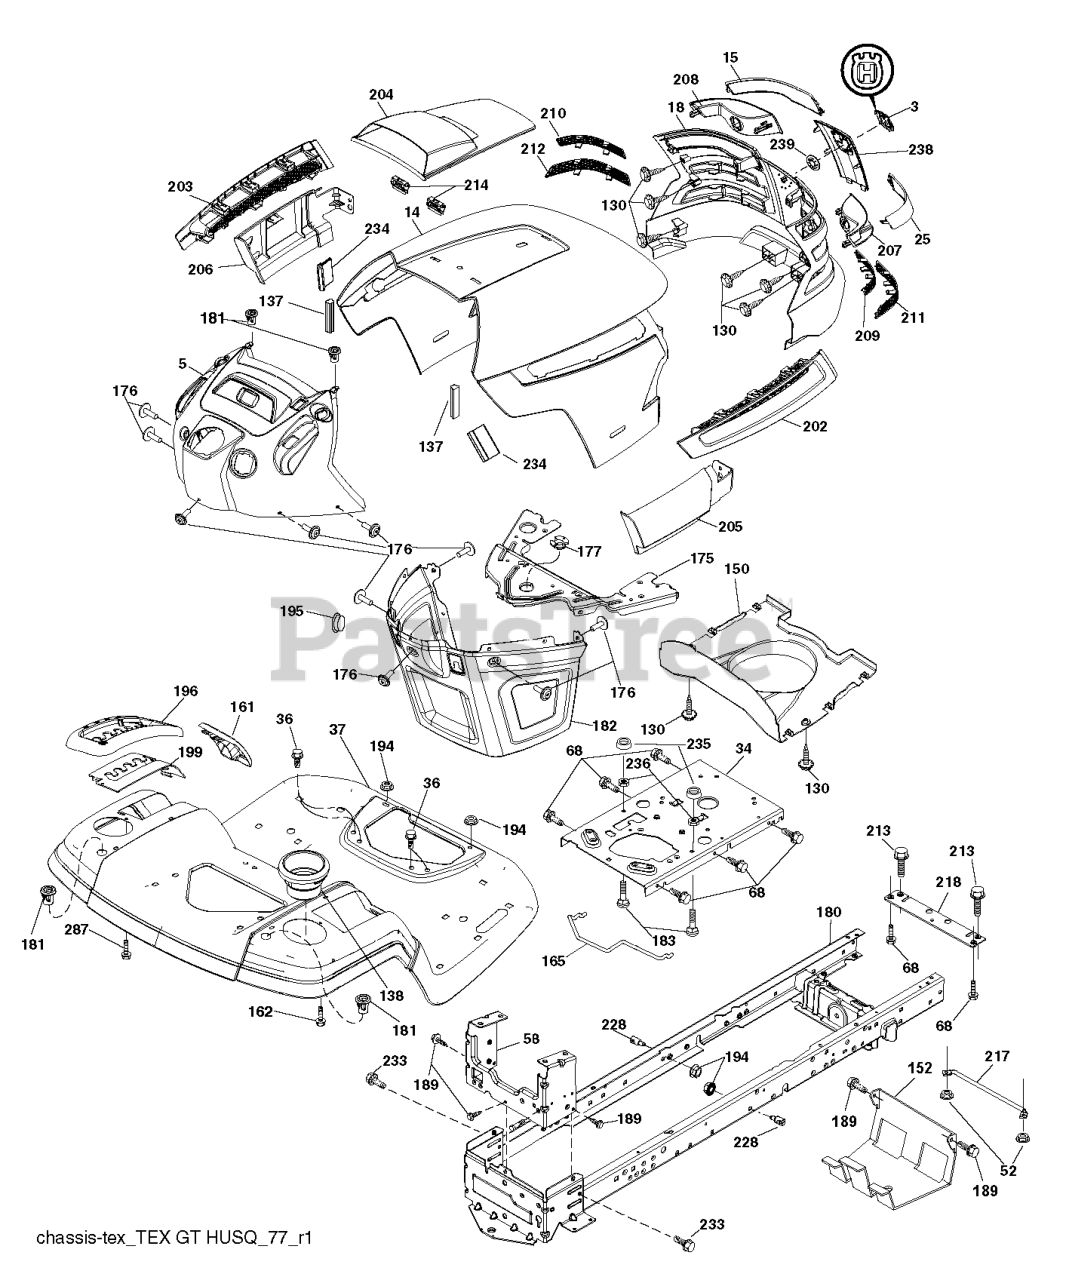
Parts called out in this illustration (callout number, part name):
3	RP LOGO
14	HOOD
15	LENS.LH.TEX.GT.HUSQ.CL
18	GRILL.ASM.HUSQ.TG/CRD.W/TRIM
25	LENS.RH.TEX.GT.HUSQ.CL
34	PLATE.ENGINE.WELDED.CHASSIS
36	SCREW 5/16"
52	LOCKNUT
58	DRAWBAR UPPER 2PC SMALL FENDER
68	Screw 5/16-18 x 1/2 Hex, Self Tapping 5/16-18 x 1/2
130	SCREW.#10 X 0.750.BOS
137	BUMPER DASH
138	CUPHOLDER.TL.TEX.418
150	AIR.DUCT.HOOD.TEX.GT.HUSQ
152	SHIELD.BROWNING.W/TEX
161	WINDOW FUEL
162	SCREW.HI-LO.CONSOLE
165	SUPPORT.TANK.REAR.W/TEX
175	PLATE.CROSSMEMBER.HUSQ
176	SCREW.#10-24X5/8.RN.QU
177	BUSHING, STEERING
180	CHASS.WLDMNT.TL.12GA/2P.48/54
181	BUSHING.MNT.FEND.CRGO.
182	DASH.LOWER.COMMON.12V.ADAPTOR
183	BOLT.5/16-18X1-1/4 FULL THD
189	SCREW
194	NUT LOCK HEX FLANGE 5/16-18
195	PLUG.HOLE.DASH.LOWER.12V.BLK
196	RP CONSOLE.ASM.DECKLFT.GR/RBT.
199	PLATE.DECK.LIFT.HUSQ.LT
202	VENT.SIDE.HOOD.HUSQ.RH.GREY
203	VENT.SIDE.HOOD.HUSQ.LH.GRAY
204	HOOD VENT
205	SKIRT.HOOD.SIDE.HUSQ.RH.GREY
206	SKIRT.HOOD.SIDE.HUSQ.LH.GREY
207	BEZEL.RH.TEX.GT.HUSQ
208	BEZEL.LH.TEX.GT.HUSQ
209	INSERT.HEX.GRILL.HUSQ.GREY
210	INSERT.HEX.GRILL.HUSQ.
211	INSERT.HEX.GRILL.HUSQ.
212	INSERT.HEX.GRILL.HUSQ.
213	BOLT
214	CLIP.RETAINER.TINNER.
217	ROD.PIVOT.HOOD
218	X-PIECE.HOOD.STOP.NON/
228	STUD.FASTNER.W/ANTI-ROTATE
233	BOLT.SHOULDER
234	BUMPER.HOOD.TEX.HUSQVARNA
235	SPACER FENDER
236	NUT.CENTERLOCK.5/16-
238	TRIM.HUSQ.TG/CRD.SERVICE
239	NUT PUSH M
287	SCREW 1/4X20
